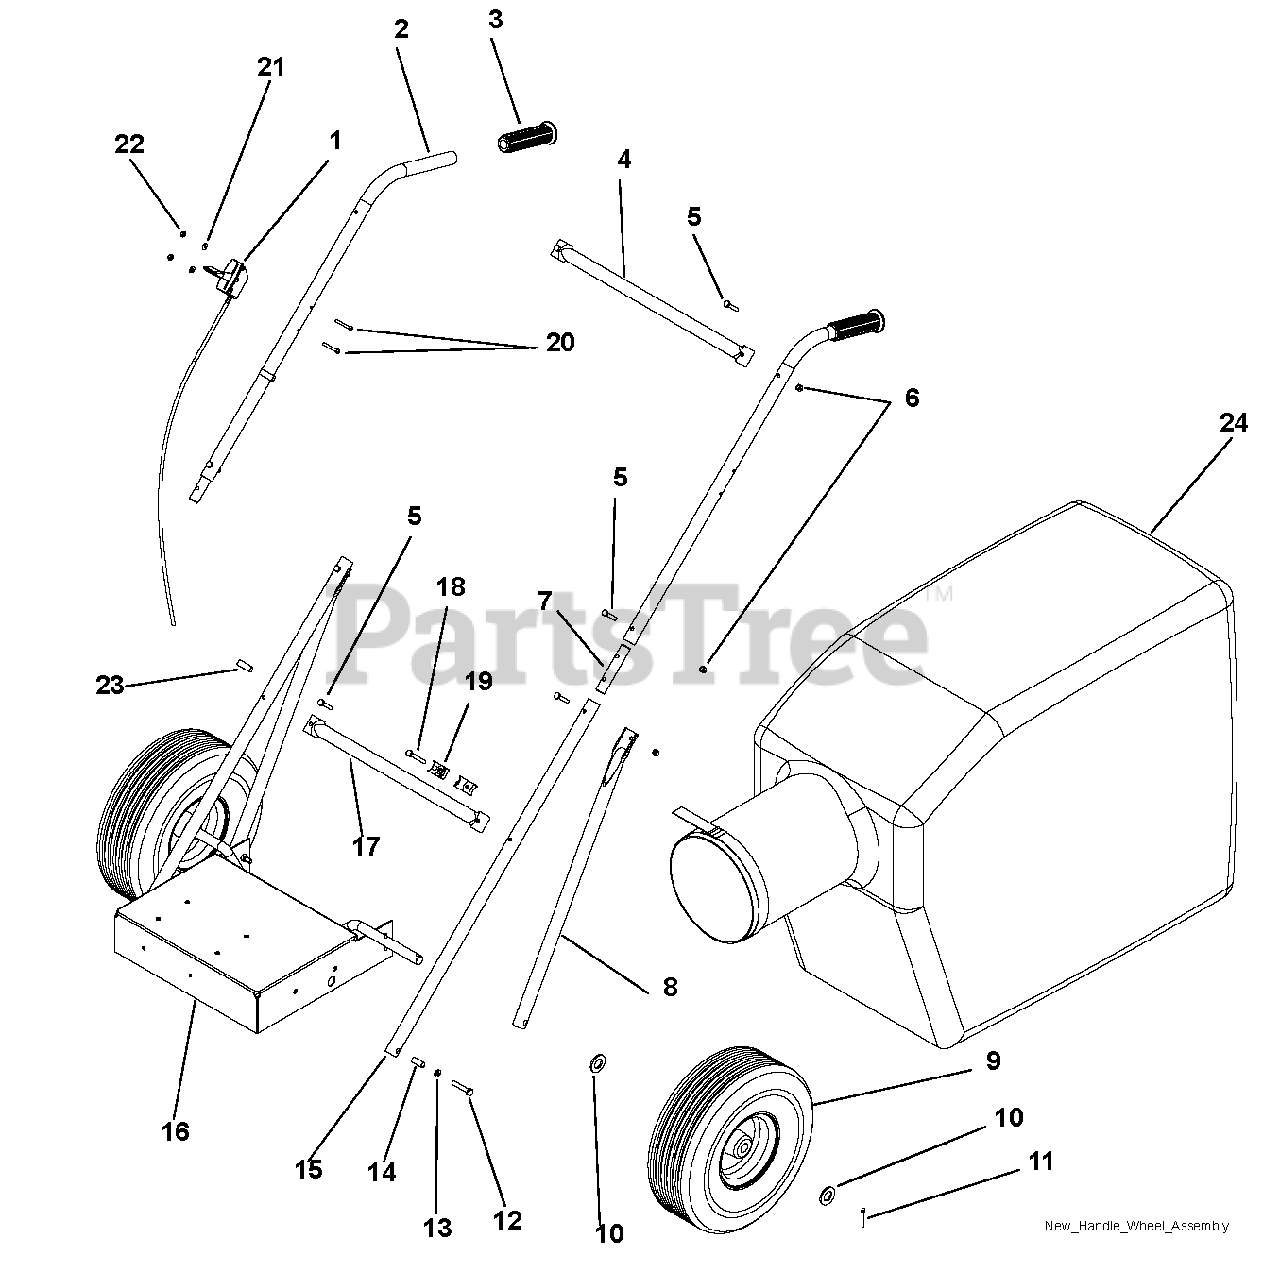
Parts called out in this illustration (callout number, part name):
1	Cable, Throttle Assembly
2	Upper Handle Vac, 35
3	Grip Handle Black
4	Tube, Upper
5	Bolt, Hex .25-20 X 1.50
6	Nut, Locking, Nylon 1/4-20
7	Handle Adapter VAC, 35
8	Handle Back Brace
9	Wheel Assembly
10	Washer, Flat Steel .812 X 1.50 X 1.35
11	Pin, Center .18 X 1.25 Extended Prong Square Cut
12	Bolt, Hex .31-18 X 1.75
13	Washer, Locking .31 X .078 Regular
14	Bushing .437 OD X 1.00 LONG
15	Lower Handle VAC, 35
16	Chasis Weldment VAC, 35
17	Crossbar Brace
18	Bolt, Hex .25-20 X 2.25
19	Buide, Rope
20	Screw, 10-24 X .75 PAN PHL MAC Stainless Steel
21	Washer, Flat Steel .219 X .50 X .049
22	Nut Locking Nylon 10-24 with Insert
23	Snap Mount
24	Collection Bag
